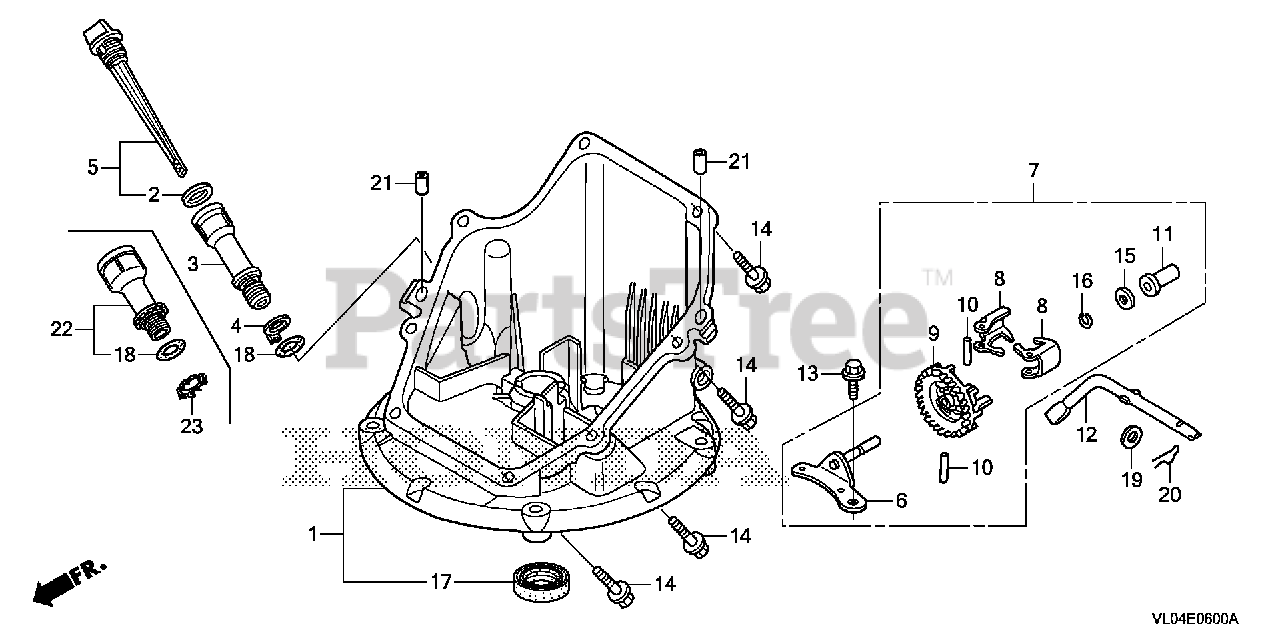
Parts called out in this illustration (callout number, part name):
1	PAN ASSY., OIL
2	GASKET, OIL FILLER CAP Use up to Engine SN 1257294.
5	DIPSTICK, OIL
6	SHAFT, GOVERNOR HOLDER
7	GOVERNOR ASSY.
8	WEIGHT, GOVERNOR
9	HOLDER, GOVERNOR WEIGHT
10	PIN, GOVERNOR WEIGHT
11	SLIDER, GOVERNOR
12	SHAFT, GOVERNOR ARM
13	BOLT, FLANGE (6X14)
14	BOLT, FLANGE (6X25) Use up to Engine SN 2056819.
15	WASHER, THRUST (6MM)
16	CLIP, GOVERNOR HOLDER
17	OIL SEAL (28X41.25X6)
18	O-RING (14.8X2.4) (ARAI)
19	WASHER, PLAIN (6MM)
20	PIN, LOCK (8MM)
21	PIN, DOWEL (8X20)
22	EXTENSION, OIL FILLER
23	WASHER, EXTENSION LOCK
